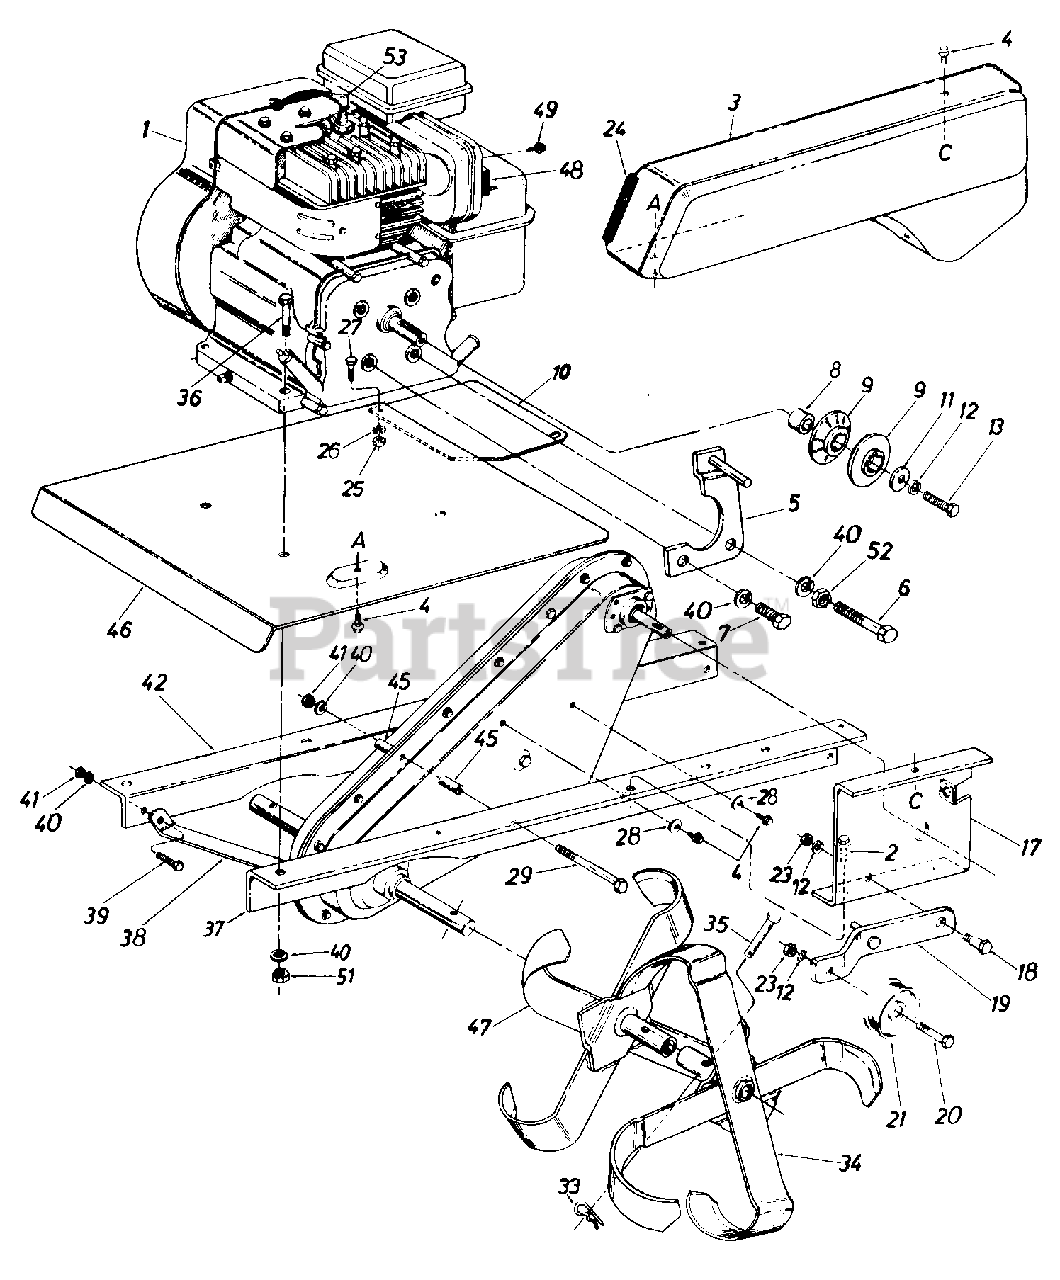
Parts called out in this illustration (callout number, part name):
1	Engine
2	Hex Self-Tap Scr. 5/16-24 x .5"
3	Belt Cover
4	Hex Self-Tap Scr. 1/4-20 x .5"
5	Belt Keeper Brkt. Ass'y.
6	Hex Bolt 5/16-24 x 2.25" Lg. (Grade 5)
7	Hex Bolt 5/16-24 x .62" Lg. (Grade 5)
8	Spacer
9	Pulley Half
10	Tine Shield Extension
11	Fl-Wash. 3/8" I.D. x 1.25"
12	L-Wash. 3/8" I.D.
13	Hex Bolt 3/8-24 x 1.00" Lg.
17	Idler Mounting Brkt.
18	Shld. Bolt
19	Idler Bracket Ass'y.
20	Hex Bolt 3/8-16 x 1.5" Lg.
21	Idler Pulley
23	Hex Jam Nut 3/8-16 Thd.
24	Trim Strip 3"
25	Hex Nut 1/4-20 Thd.
26	L-Wash. 1/4" I.D.*
27	Hex Bolt 1/4-20 x .62 Lg.*
28	Bell-Wash. .26 I.D. x .75 O.D.
29	Hex Bolt 5/16-18 x 3" Lg.*
33	Hairpin Cotter
34	See Tine Chart
35	Clevis Pin
36	Hex Bolt 5/16-18 x 1.5" Lg.*
37	Frame Rail L.H.
38	Front Brace Brkt.
39	Hex Bolt 5/16-18 x .75" Lg.*
40	L-Wash. 5/16" I.D.*
41	Hex Cent. L-Nut 5/16-18 Thd.
42	Frame Rail R.H.
45	Spacer
46	Tine Shield
47	See Tine Chart
48	Deflector
49	Hex Self-Tap Scr. #8-32 x .38"
51	Hex Nut 5/16-18 Thd.*
52	Hex Nut 5/16-24 Thd.*
53	Spark Plug Boot
